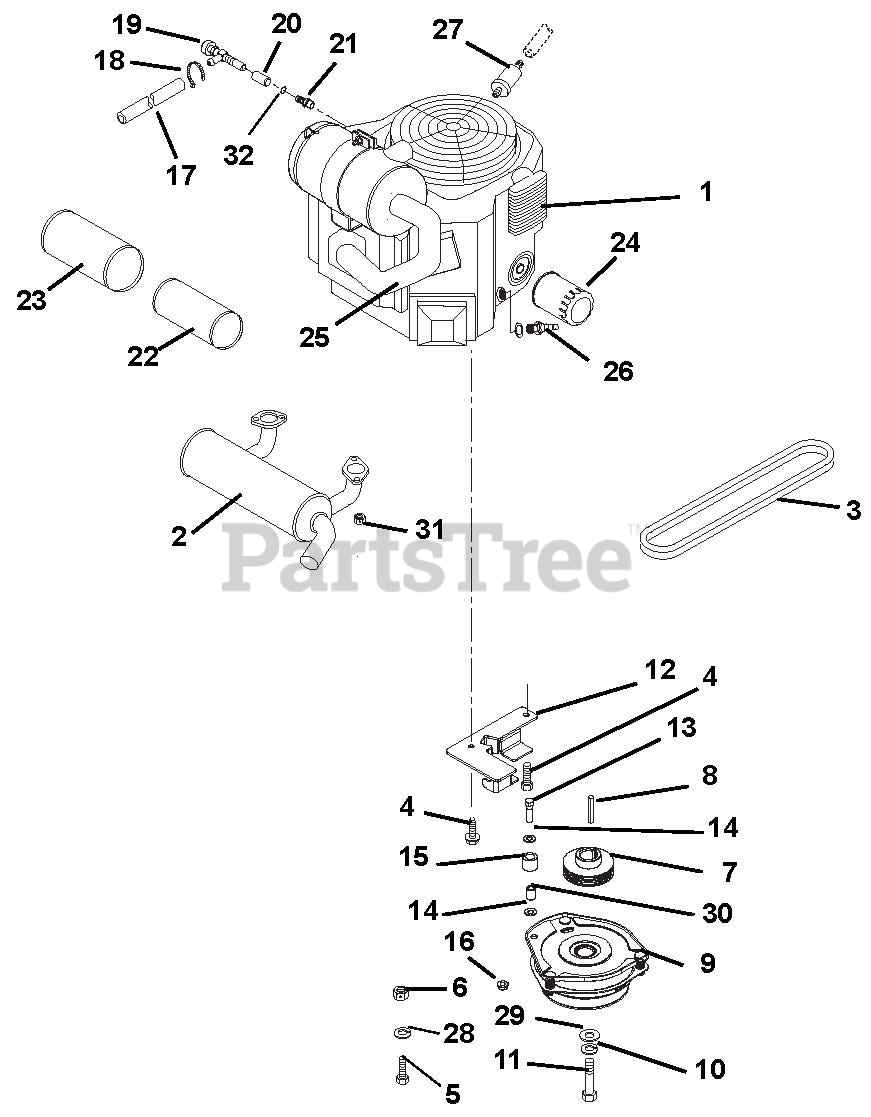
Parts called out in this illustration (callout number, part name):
1	Engine, Liquid Cooled Kawasaki
1	Engine, Kohler
1	Engine, Kawasaki
1	Engine, Kohler Command Pro
2	Muffler, Kawasaki Vertical
2	Muffler, Kawasaki Liquid Cooled
2	Muffler, Kohler Twin
3	Belt, Poly-V
4	Screw, Tapping Hex Washer Head .38-16 x 1.50
4	Bolt, Hex M8-1.25 x 25 Grade 8
4	Bolt, Hex .38-16 x 1.25 FTH G5 EP30
5	Bolt, Hex .31-18 x 1.75 Grade 5
6	Nut, Locking Top Flange .31-18
7	Sheave, Poly V 1.127 x 3.275
8	Key, Square .25 x 3.50 x .25 SA
9	Clutch, Electric
10	Washer, Locking .44 x .109
11	Bolt, Hex .44-20 x 3.00 Grade 5 YZ EP80
11	Bolt, Hex .44-20 x 1.50 Grade 5 YZ EP80
11	Bolt, Hex M10 x 1.5 x .75 10.9 EP80
12	Anchor, Clutch
13	Bolt-Hex .38-16 x 1.50 Grade 5
14	Washer-Flat-Steel .406 x .812 x .065
15	Bumper, Rubber .62 x 1.0 x .88 LG
16	Nut, Locking-Top-Flange .38-16
17	Gas Line, Bulk .25 I.D.
18	Cable Tie LG 5-1/2
19	Drain, 1/2" Drain
20	Adapter, .38 NPTF
20	Adapter, M20F- .375 NPT
21	Nipple, Pipe .375-18 NPTF x 3.00
22	Element, Inner Safety
23	Element, Outer Primary
24	Oil Filter
25	Hose, Air Intake
26	Spark Plug
27	Fuel Filter
28	Washer, Locking-EXT.326 x .599 x .031
29	Washer, Flat Steel .469 x 2 x .25
29	Washer, Flat Steel .422 x 2.00 x .25
30	Bushing, .407 x .625 x .813
31	Nut, Locking, Top M8-1.25
32	O-Ring
